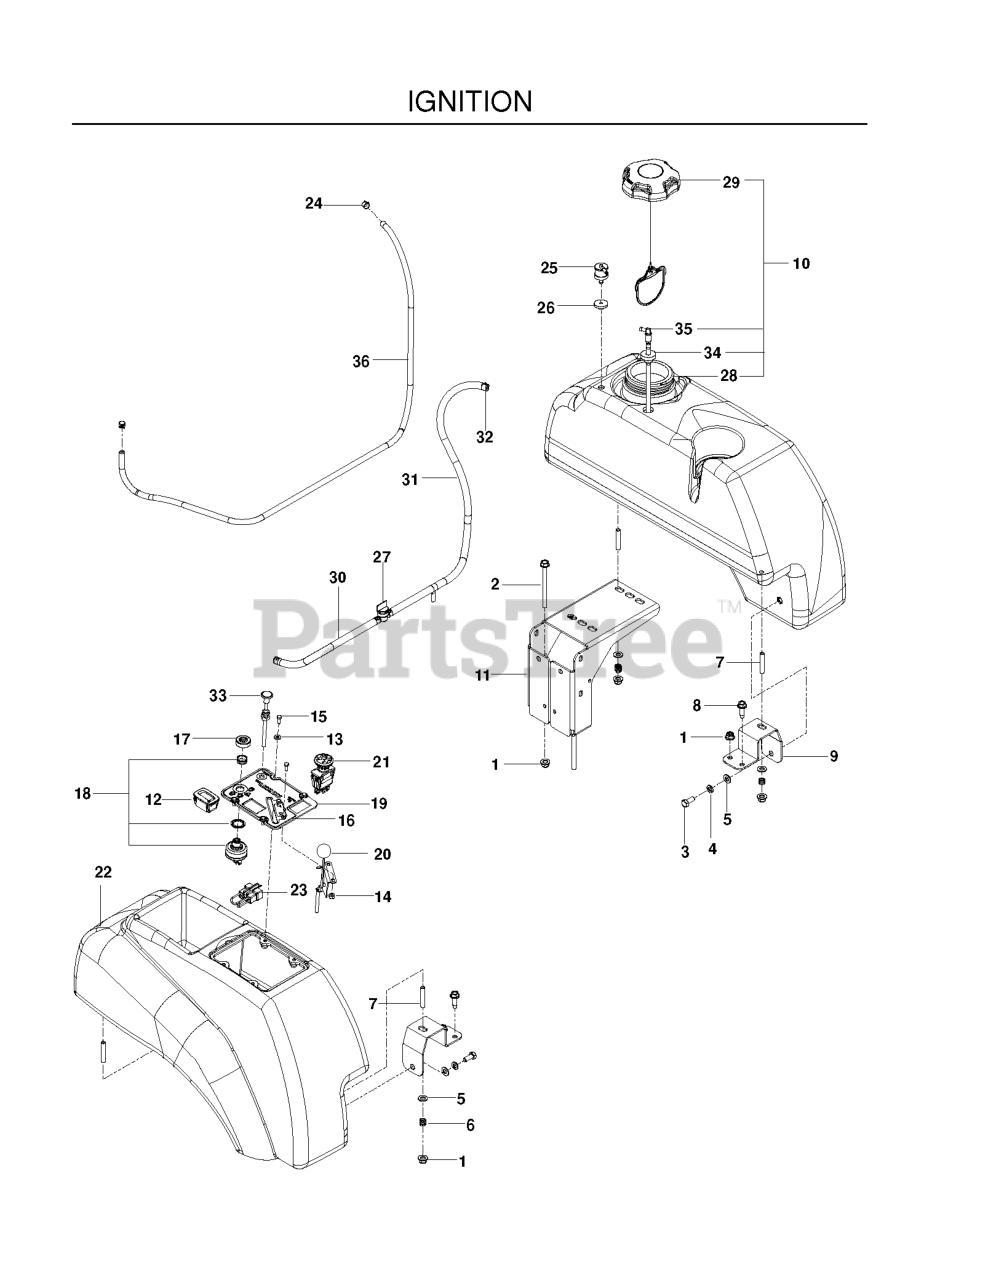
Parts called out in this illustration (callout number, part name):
1	5/16-18 NYLOC FLANGE NUT
2	HHFS 5/16-18 X 3 3/4
3	HCS 5/16C X 3/4
4	WASHER.LOCK.HVY.HLCL.SPR.5/16
5	FLAT WASHER 5/16 SAE
7	STUD, 5/16C
8	RP BLT 5/16-18 X 1 THRD FORM D
9	SUPPORT, TANK, BLK
10	ASSEMBLY, LT TANK, EPA GRAY
11	MOUNT, TANK, ZT BLK
12	HOUR METER
13	WASHER #10
14	NUT 10-24 NYLOC
15	HCS #10-24 X 1/2
16	DECAL, CONSOLE HUS
17	CAP IGNITION NUT
18	SWITCH, IGNITION, INDAK
19	PLATE.CONSOLE.BLACK
20	THROTTLE CONTROL W/BALL KNOB
21	SWITCH, PTO 10 AMP
22	FENDER CONSOLE
23	PLUG, TIMER
24	CLAMP, HOSE
25	VALVE.FUEL.CHECK
26	GROMMET, CHECK VALVE
27	FUEL VALVE
28	TANK, FUEL, LT-EPA
29	CAP, FUEL
30	HOSE, FUEL .25 ID X 26"
31	GAS LINE 10"
32	HOSE CLAMP
33	CABLE, CHOKE
34	RUBBER GROMMET
35	FITTING, FUEL
36	HOSE, VAPOR 3/16 X 48"
